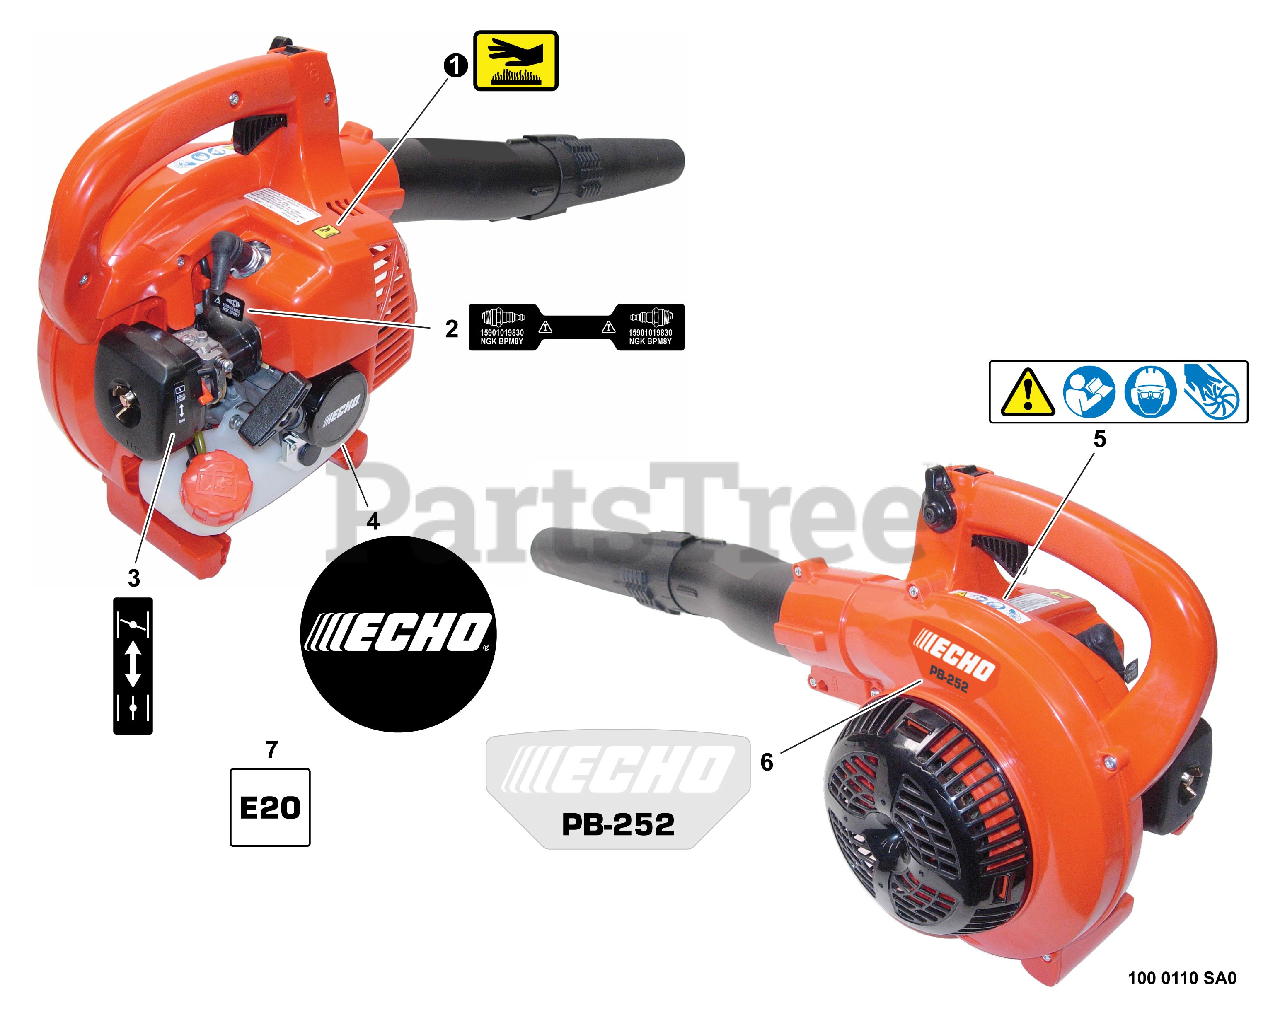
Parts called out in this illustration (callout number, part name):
1	LABEL - HOT SURFACE
2	LABEL - SPARK PLUG -- BPM-8Y
3	LABEL - CHOKE
4	LABEL - ECHO
5	LABEL - CAUTION
6	LABEL - MODEL PB-252
7	LABEL - E20
